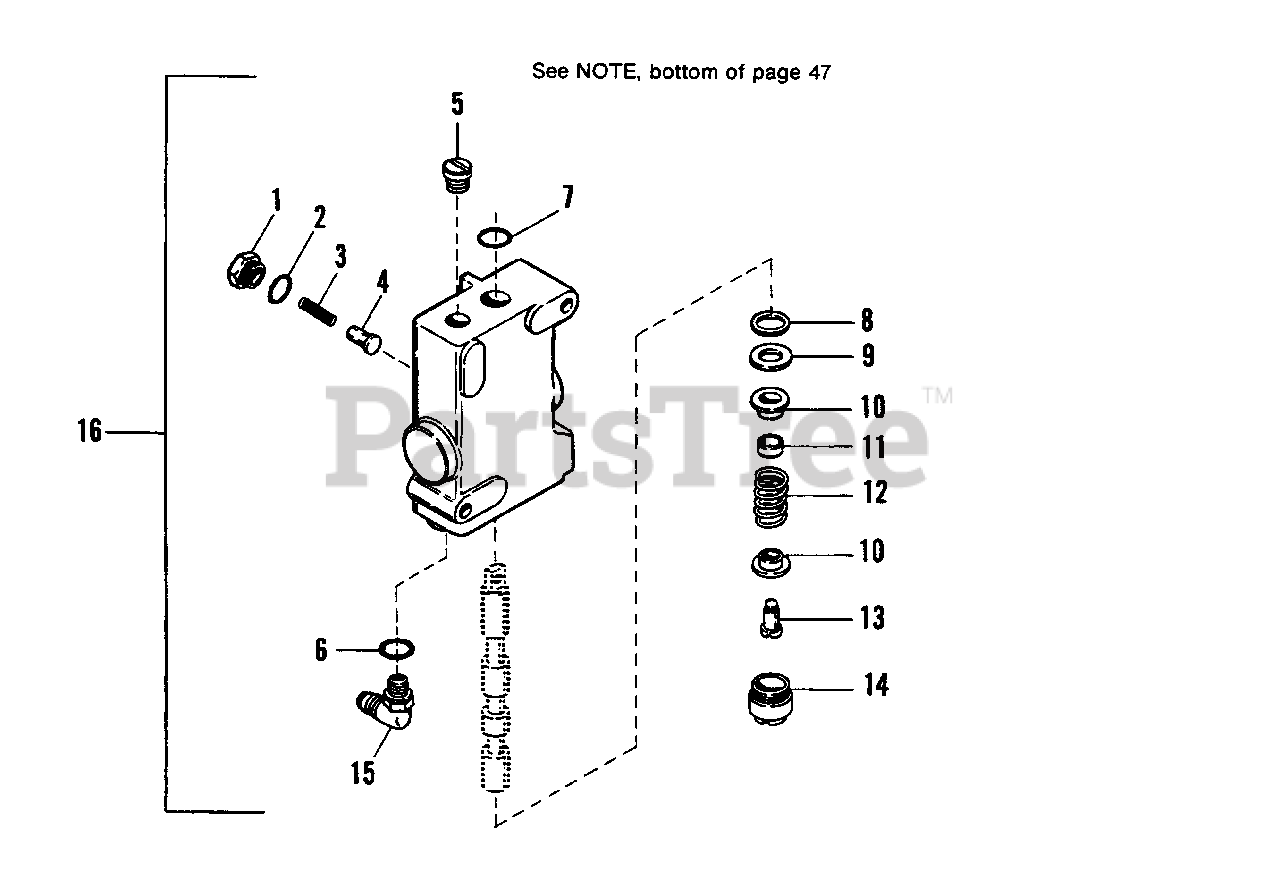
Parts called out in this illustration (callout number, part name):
1	Plug, Check
8	QUAD RING
10	SEAT, Spring
11	STOP, Spool
13	STEM, Spool
16	VALVE ASSY., Complete
